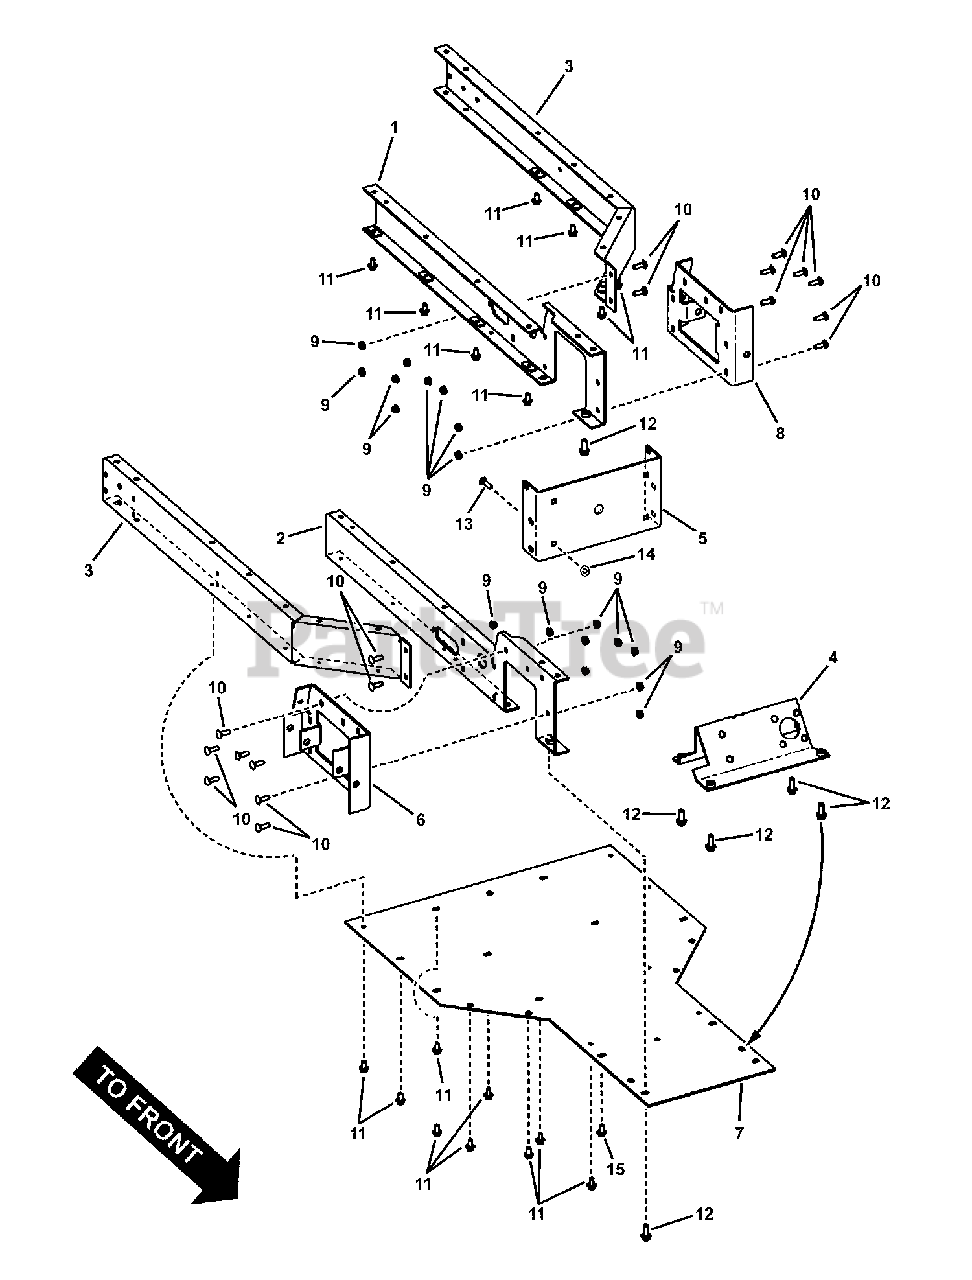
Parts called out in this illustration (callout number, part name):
1	WELDMENT, Inner LH Frame Rail
2	WELDMENT, Inner RH Frame Rail
3	WELDMENT, Outer CVT Frame
4	WELDMENT, Steering Bracket
5	END, Frame
6	SUSPENSION PIVOT, RH
7	STIFFENER, Frame
8	SUSPENSION PIVOT, LH
9	NUT, 5/16-18 Hex Flange Lock, GR 5
10	BOLT, 5/16-18 x 1" Square Neck Carriage, GR5
11	BOLT, 5/16-18 x 5/8" Hex Flange Lock, GR 5
12	BOLT, 3/8-16 x 1" Hex Flange Lock, GR 5
13	BOLT, 3/8-16 x 1-1/4" Short Square Neck Carriage, GR 5
14	RETAINER, 3/8" Bolt
15	BOLT, 3/8-16 x 3/4" Hex Flange Lock, GR 5
